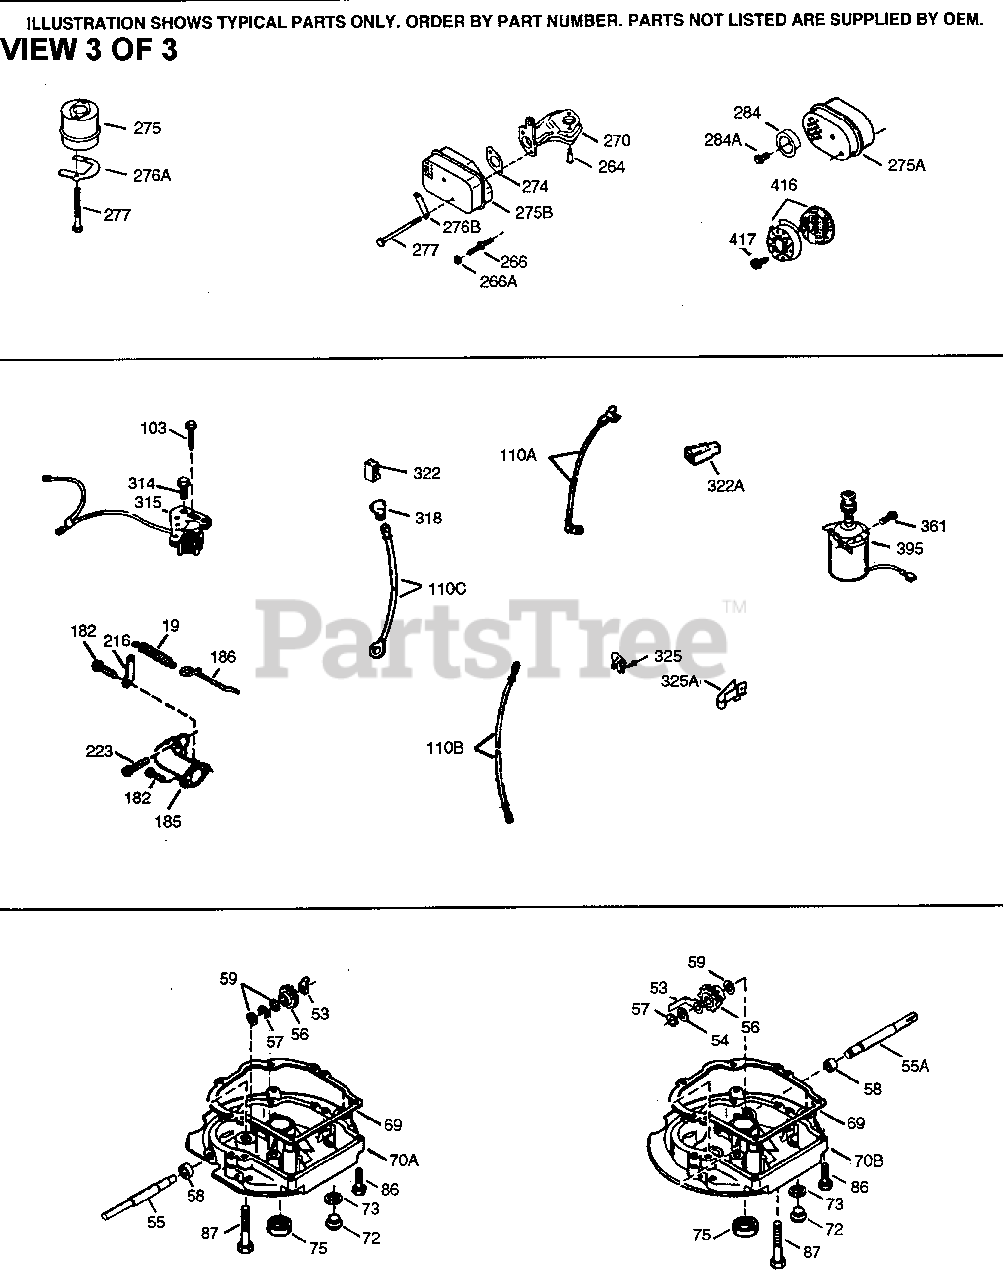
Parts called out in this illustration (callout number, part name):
19	Extension Spring
69	* Mounting Flange Gasket
72	Oil Drain Plug
75	Oil Seal
86	Screw, 1/4-20 x 1-1/4"
103	Screw, Torx T-15, 10-24 x 1"
182	Screw, 1/4-28 x 7/8"
185	Intake Pipe (Incl. 224)
186	Governor Link
223	Screw, 1/4-20 x 1"
264	Screw, Torx T-30, 1/4-20 x 1-7/32"
266A	Nut & Lock Washer 1/4-28
270	Exhaust Manifold
275	Muffler
277	Screw, 5/16-18 x 2-1/2"
325	Wire Clip
